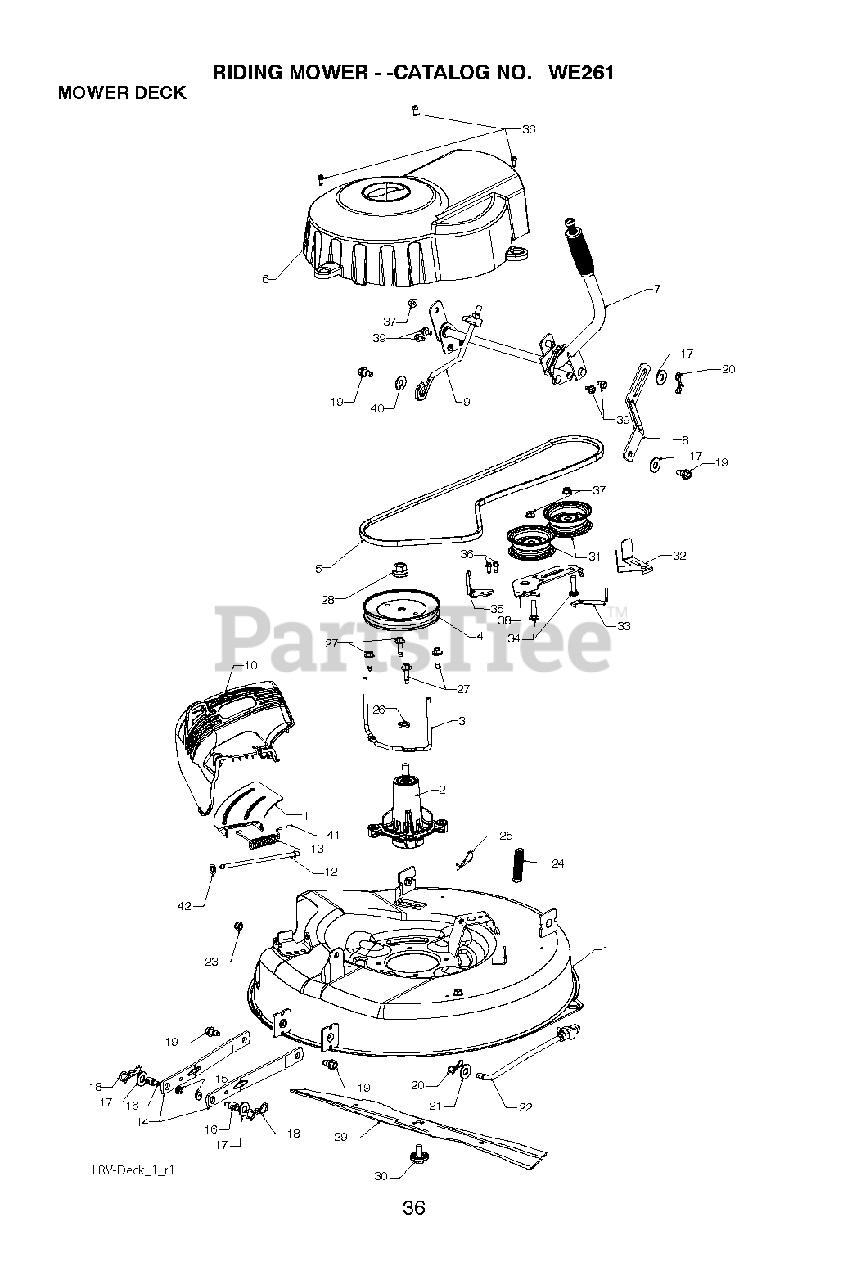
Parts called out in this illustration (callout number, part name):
1	DECK, 26"
2	MANDREL.ASM.SUB-NON.GR
3	KEEPER.BELT.MANDREL.PULLEY
4	PULLEY.MANDREL
6	COVER, MANDREL
7	LIFT.ASM.DECK.LRV
8	LINK, DECK LIFT
9	LINK.ASM.LIFT.ADJUSTABLE
11	SUPPORT, DEFLECTOR
12	ROD.HINGE
13	SPRING.TORSION.DEFLECT
14	ARMS.SUSP.MOWER.REAR.SRD
15	NUT LOCK HEX FLANGE 5/16-18
16	STUD.FASTNER.W/ANTI-ROTATE
17	WASHER.CLEAR.ZINC
18	PIN.COTTER.7/16.BOW TI.
19	BOLT.SHOULDER
20	PIN.COTTER.5/16.BOW TI
22	LINK.ASM.TOP.DECK.LRV
23	LOCKNUT
24	SPRING.EXTENSION.DECK.LRV
26	WASHER.SPACER.MANDREL
27	SCREW, WASHER HEAD
28	NUT.FLANGE.LOCK.TOP
29	BLADE.26"
30	BOLT.WASHER.ASM.7/16-2
31	PULLEY.IDLER.48"PRIMARY
32	GUARD, BELT
33	KEEPER BELT
34	BOLT.3/8-16X1.50
35	ARM BRAKE MOWER RH
36	SCREW.1/4-20X5/8
37	NUT LOCK FLG 3/8-16 UNC
38	ARM, IDLER
39	SCREW LT
41	CAP-SLEEVE LT
42	NUT PUSH M
43	GRIP HANDLE
44	PLUNGER.ASM.LRV
45	PIN GROOVE.
47	PLUNGER BUT KIT
48	KEEPER.BELT
49	SPACER.RETAINER
50	SCREW 3/8-16X1
51	BUMPER.HOOD.TEX.HUSQVARNA
52	SCREW 3/8-16X1/2
